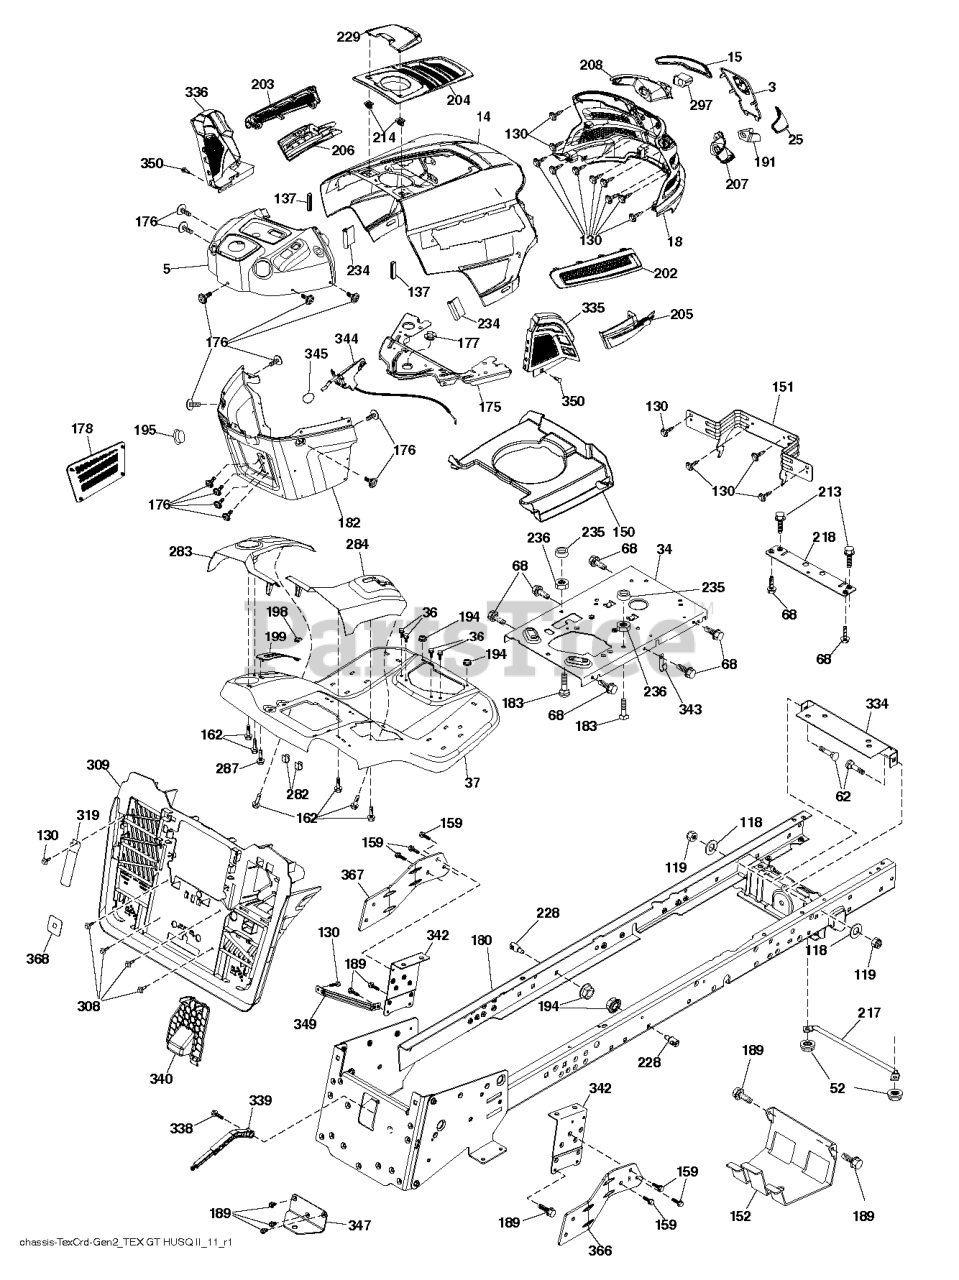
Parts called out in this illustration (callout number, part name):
3	APPLIQUE.SUBASM.GT.HUSQ.II
14	HOOD.ASM.HUSQVARNA.GT.TEX.ORAN
15	LENS.HEADLIGHT.LH.GTII.2011
18	GRILLE.SUBASM.GT.HUSQ.II
25	LENS.HEADLIGHT.RH.GTII.2011
34	PLATE.ENGINE.WELDED.CHASSIS
36	SCREW 5/16"
37	FENDER.TEX.SRD.CRD.FRN.GUARDS
52	LOCKNUT
68	SCREW LT
130	SCREW.#10 X 0.750.BOS
137	BUMPER DASH
150	AIR.DUCT.GTV.BLACK
151	BRACKET.PIVOT.HOOD.GT.HUSQ.II
152	SHIELD.BROWNING.PNT.GT.V2
159	SCREW, 3/8-16X3/4
162	SCREW.HI-LO.CONSOLE
175	PLATE.CROSSMEMBER.HUSQ
176	SCREW.#10-24X5/8.RN.QU
177	BUSHING, STEERING
178	CARGO.ASM.NET.TXGT.W/C
182	DASH DASH LOWER
183	BOLT.5/16-18X1-1/4 FULL THD
189	SCREW
191	INSERT.REFLECTIVE.RH.HUSQ.GTII
194	NUT LOCK HEX FLANGE 5/16-18
195	PLUG.HOLE.DASH.LOWER.12V.BLK
198	INDICATOR.DECK.LIFT.RED
199	PLATE DECK LIFT
202	VENT.SIDE.RH.GT.HUSQ.II.
203	VENT.SIDE.LH.GT.HUSQ.II.498
204	VENT.TOP.EXTERNAL.FILL.GT2.GRE
205	SIDE.TRIM.RH.GT.HUSQ.II
206	SIDE.TRIM.LH.GT.HUSQ.II.GRAY
207	BEZEL LIGHT.RH.GT.II.MYLAR
208	BEZEL LIGHT.LH.GT.II.MYLAR
213	BOLT
214	CLIP.RETAINER.TINNER.
217	ROD.PIVOT.HOOD
218	X-PIECE.HOOD.STOP.NON/
228	STUD.FASTNER.W/ANTI-ROTATE
229	LID.EXT.FILL.GT.HUSQ2.BLACK
234	BUMPER.HOOD.TEX.HUSQVARNA
235	SPACER FENDER
236	NUT.CENTERLOCK.5/16-
282	CLIP.RETAINER.CONSOLE.LT.HUSQ
283	CONSOLE.DECKLIFT.CRDII.498
287	SCREW 1/4X20
297	INSERT.REFLECTIVE.LH.HUSQ.GTII
308	BOLT.5/16-18UNCX3/4 W/SEMS.BLK
309	BACKPLATE.SUBASM.SERV.TEX.CRD.
319	LEVER.BAGGER.TEX.CRD.GEN.BLACK
335	COVER-LH.LOWER.DASH.GT2.BLACK
336	COVER.LOWER.DASH.RH.BLACK
338	BOLT BOLT SHOULDER
339	LEVER LEVER BAGGER
340	BATTERY.DOOR.TEX.CRD.GEN.2,1
342	SUPPORT SUPPORT FENDER
343	CLIP CLIP
344	CONTROL.EZ.MULCH.TEX/CRD
345	RP KNOB.OVAL.TAPERED.3/8-16BLK
347	HITCH HITCH TOW TEX CRD GEN 2
349	BRACKET.SUPPORT.LRVB/CRD
350	CLIP.X-MAS.TREE
366	BRACKET.RH.FRONT.BAGGER.BLACK
367	BRACKET.LH.FRONT.BAGGER.BLACK
368	FULL.LEVER.BAGGER.TEX.CRD
